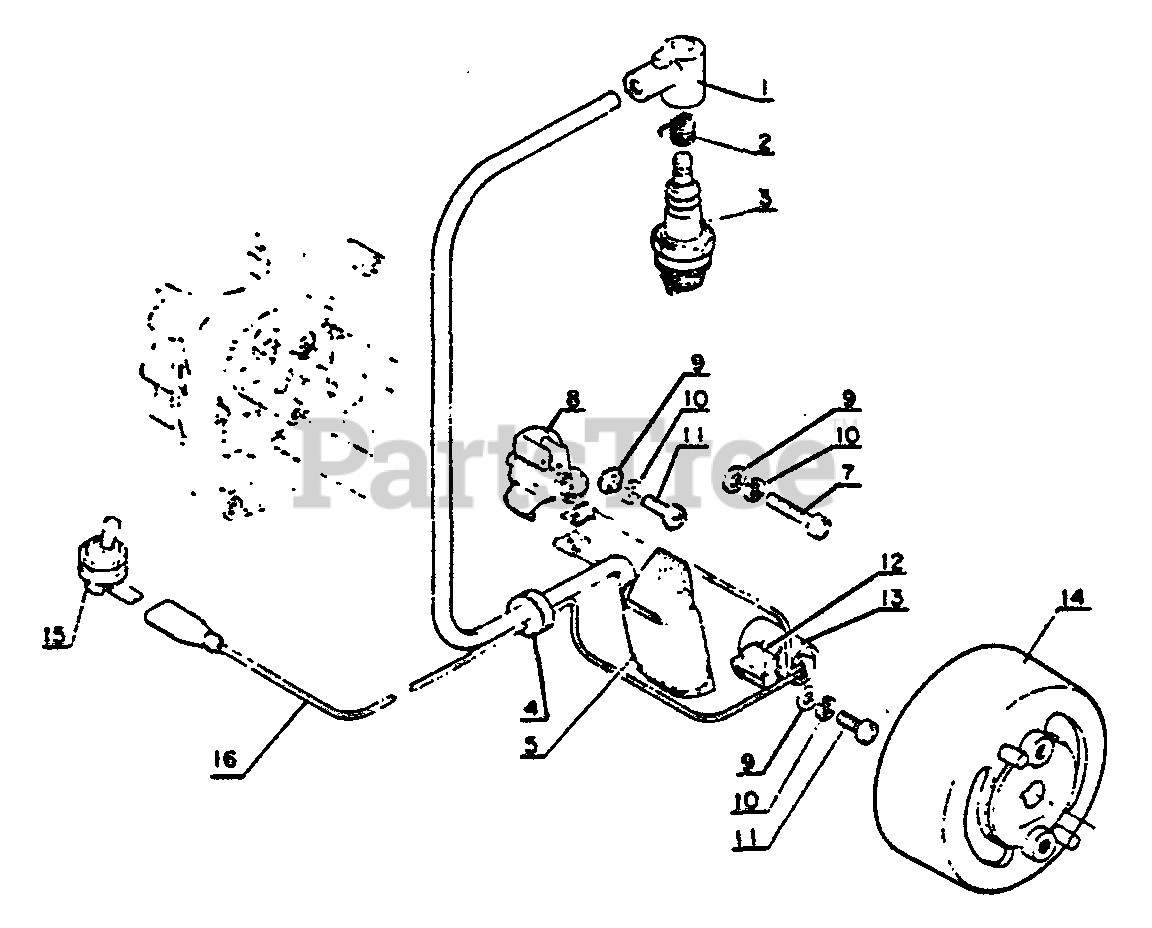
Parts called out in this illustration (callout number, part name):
1	CAP, SPARK PLUG
2	TERMINAL, SPARK PLUG CAP
3	SPARK PLUG -- BM-6A
5	COIL, IGNITION
7	SCREW - 4X25
8	CONTACT POINT SET
9	WASHER - 4
10	LOCKWASHER - 4
11	SCREW - 4X10
12	PAD, OIL
13	CONDENSER
14	FLYWHEEL
15	SWITCH, IGNITION
16	LEAD - IGNITION
